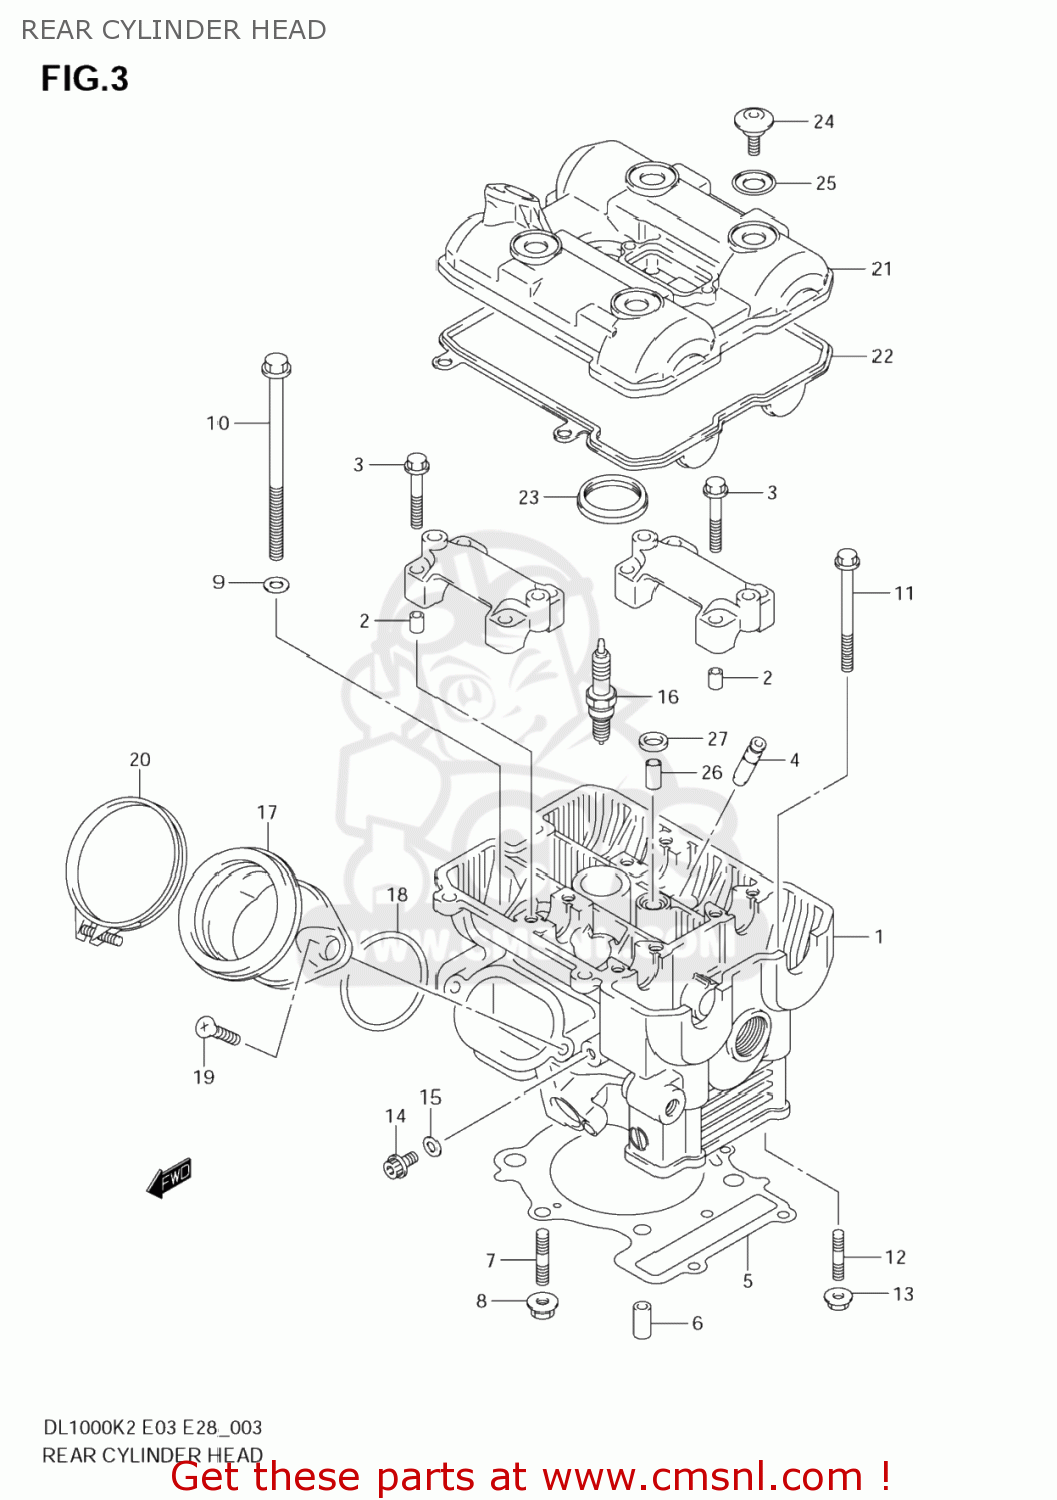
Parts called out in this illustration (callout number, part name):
1	HEAD ASSY,CYLINDER FR
2	PIN(6.2X8X11)
3	BOLT(6X39)
4	GUIDE,VALVE
5	GASKET,CYLINDER HEAD (NAS)
6	PIN
7	BOLT,STUD
8	NUT
9	WASHER(10.5X19X2)
10	BOLT(10X175)
11	BOLT(6X70)
12	BOLT,STUD
13	NUT
14	BOLT
15	GASKET(5.8X13X1.2) (NAS)
16	PLUG,SPARK(CR8EK)
17	PIPE ASSY,INTAKE RR
18	O RING(D:2.4,ID:55.6)
19	SCREW ,6X16
20	CLAMP
21	COVER,CYLINDER HEAD RR
22	GASKET,CYL HEAD COVER NO.1 (NAS)
23	GASKET,CYL HEAD COVER NO.2
24	BOLT(7X17.5)
25	WASHER(10.6X25.5X2.3)
26	PIN(6.2X8X16)
27	GASKET,2ND AIR PASSAGE (NAS)
